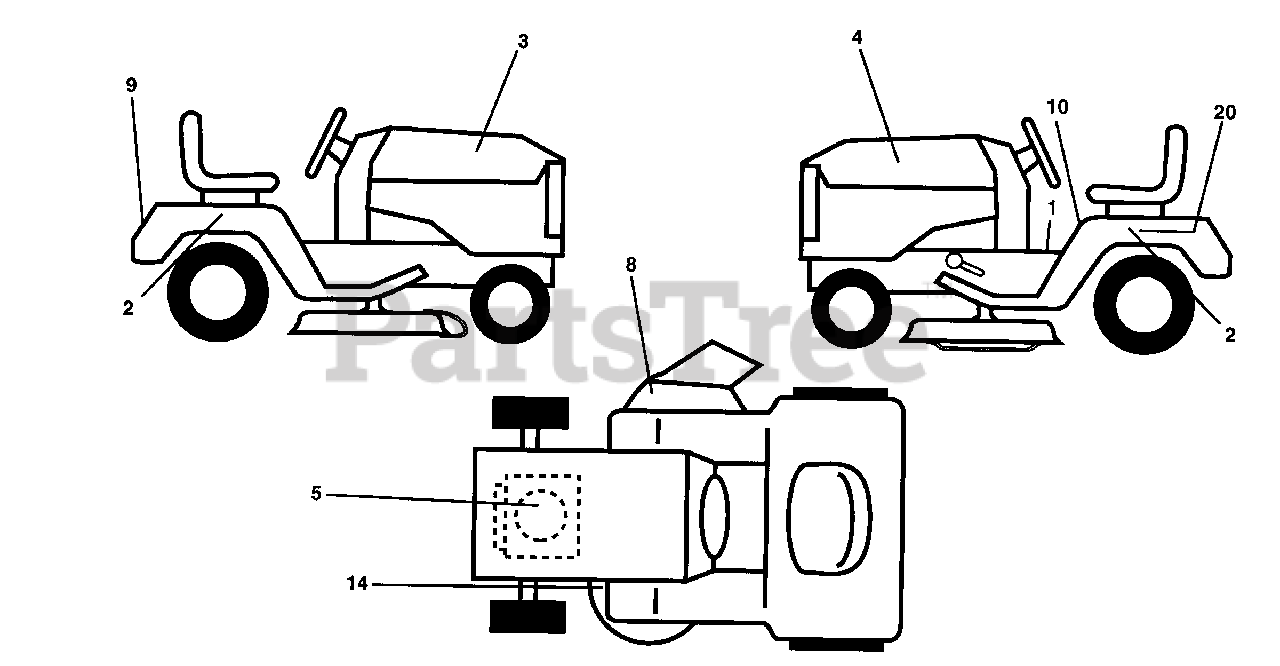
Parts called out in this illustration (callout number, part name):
1	Decal Oper. Step Thru Eng/Fr
2	Decal Fender Auto Husq Radius
3	Decal Hood LH
4	Decal Hood RH
5	Decal HP Engine
8	Decal Warning
9	Decal Fender Husq
10	Decal Fender Danger Eng/Fr
14	Decal V-Belt Schematic
20	Decal Bat Dan/Psn
MK380	Mulcher Kit with Blades
